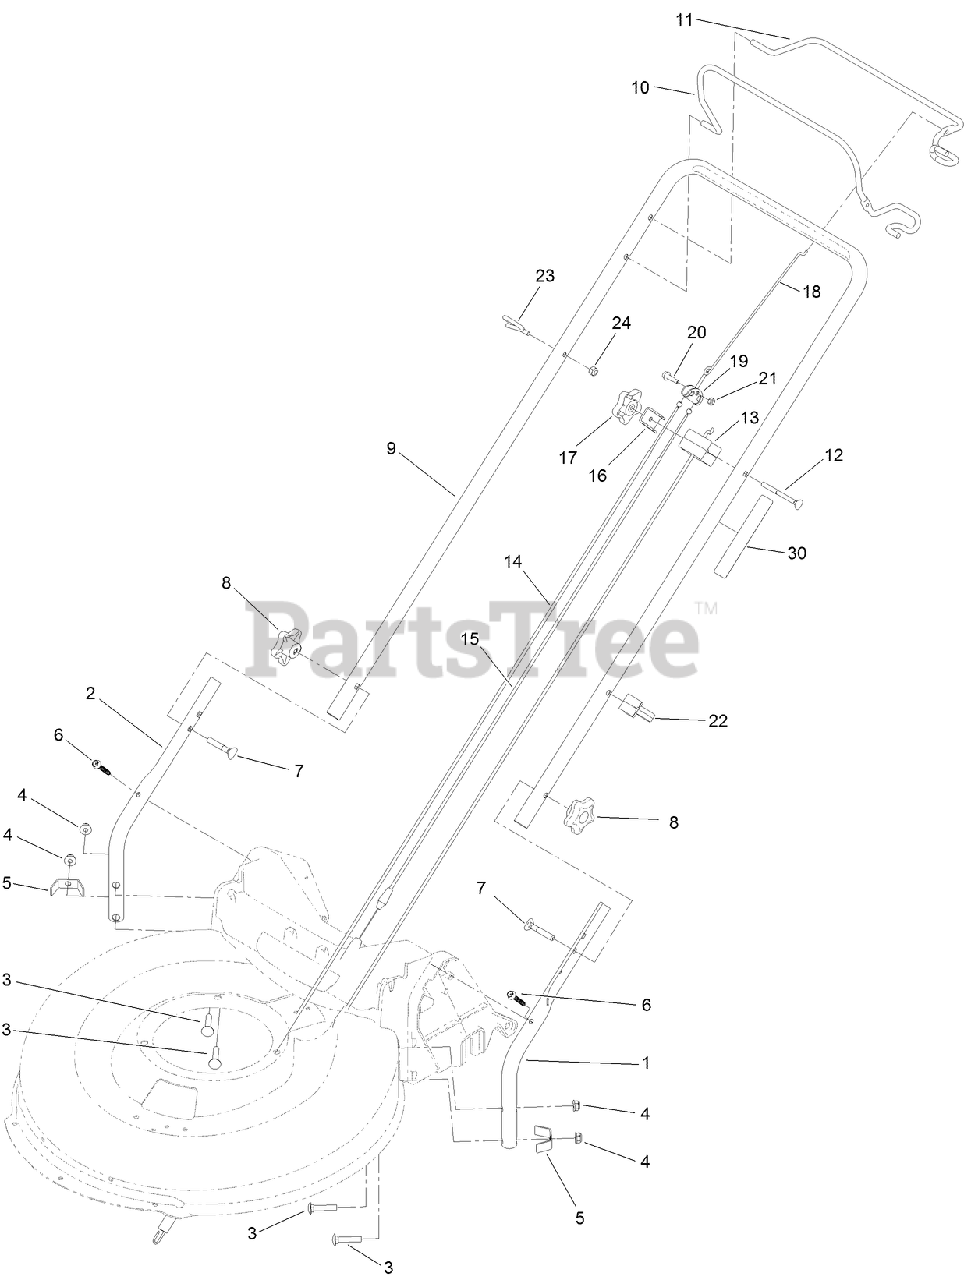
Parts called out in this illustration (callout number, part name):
3	BOLT-CARR
4	NUT-FLANGE, NI
5	BRACKET-CHUTE
6	SCREW-FLANGE, SERRATED
7	SCREW-HANDLE
8	KNOB-HANDLE
9	HANDLE-UPPER
11	BAIL-TRACTION
12	SCREW-HANDLE
13	CABLE-BRAKE
14	CABLE-TRACTION, FRONT
15	CABLE-TRACTION, REAR
16	CLAMP-CABLE
17	KNOB-HANDLE, LOCKING
18	LINKAGE, EQUALIZER
19	YOKE-CABLE
20	SCREW-SHOULDER
21	NUT-LOCK, NI
22	GUIDE-CABLE
23	GUIDE-ROPE
24	NUT-LOCK, NI
30	DECAL-TRACTION, ADJUST
